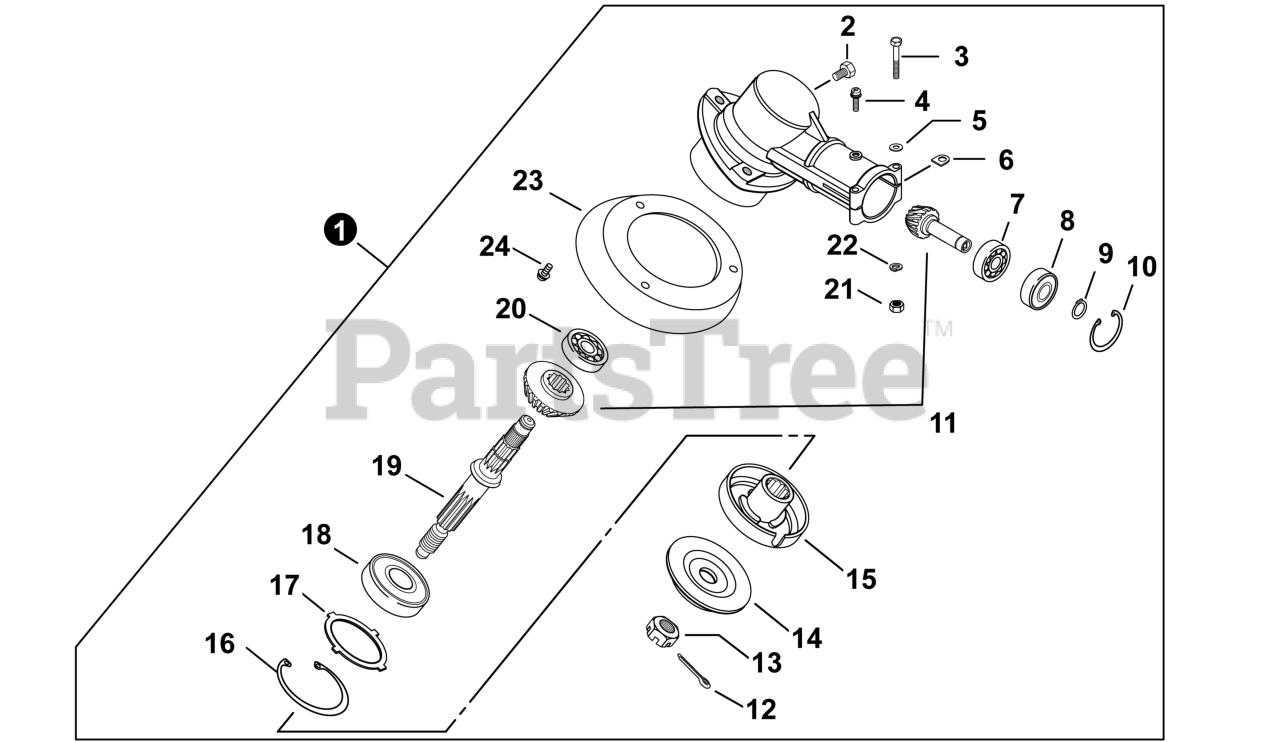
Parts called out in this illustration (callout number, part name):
1	GEAR CASE ASSY
2	BOLT M8x8
3	BOLT HSH CB-5x35
4	SCREW 5x10
5	WASHER, FLAT 5.5x10x0.8
6	D-WASHER
7	BEARING, BALL 6900
8	BEARING, BALL 6900Z
9	RING, SNAP 10
10	RING, SNAP 22
11	GEAR SET
12	PIN, COTTER 2x22
14	PLATE, ADAPTOR - LOWER
15	PLATE, ADAPTOR - UPPER
16	RING, SNAP 32
18	BEARING, BALL 6201
19	SHAFT, GEAR
20	BEARING, BALL 609
22	WASHER, FLAT 5.5x10x0.8
23	COVER, GEAR CASE
24	SCREW 5x20
